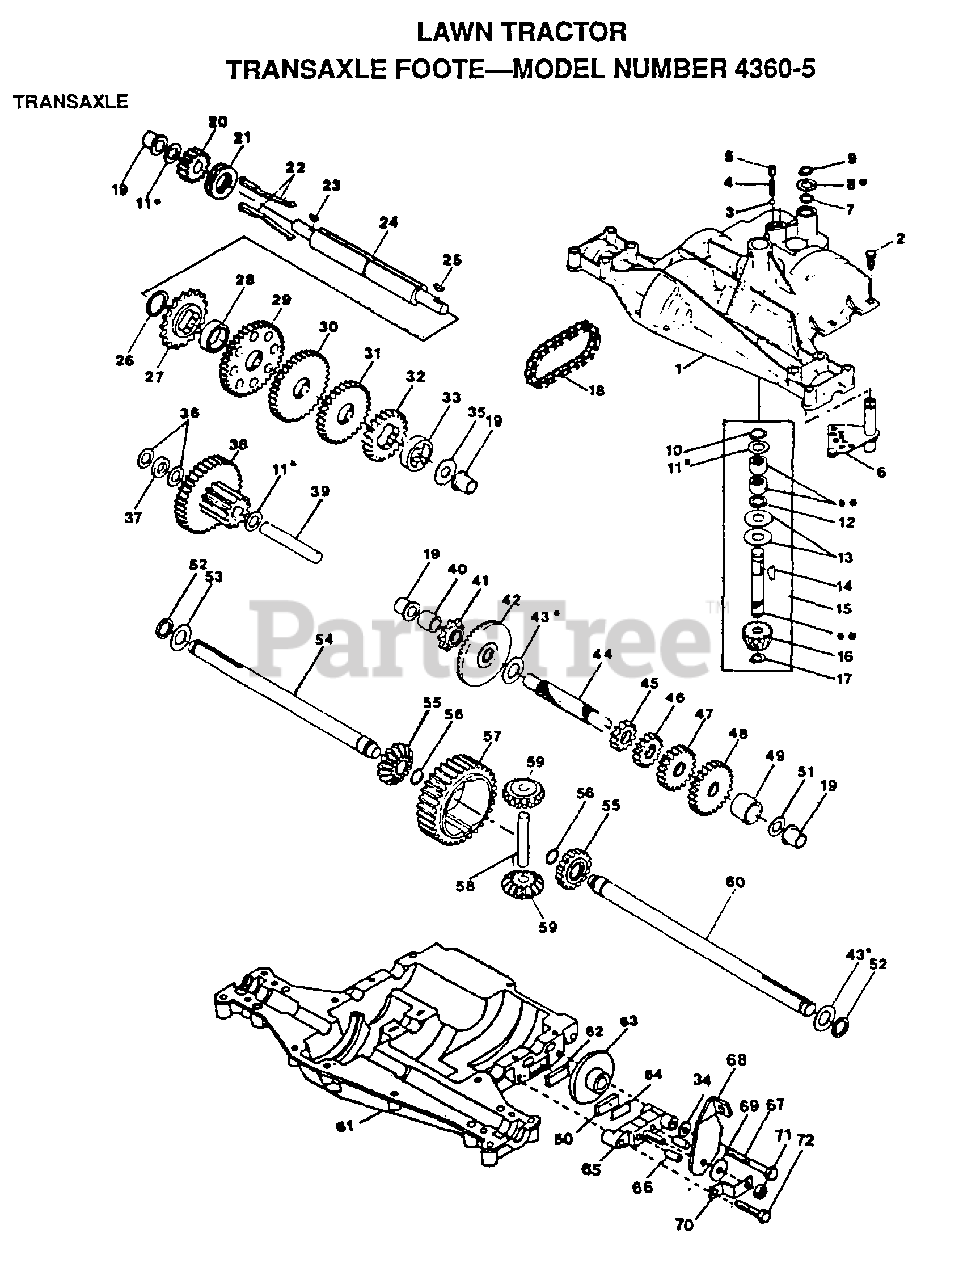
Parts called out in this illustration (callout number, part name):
1	HOUSING UPPER
3	BALL DETENT
4	SPRING, DETENT
5	SCREW, SET
6	ASSY SHIFTER
8	WASHER PLAIN
8A	WASHER PLAIN
8B	WASHER PLAIN
8C	WASHER PLAIN
8D	WASHER PLAIN
8E	WASHER PLAIN
8F	WASHER PLAIN
9	RING RETAINING
10	RING RETAINING
11	WASHER PLAIN
11A	WASHER PLAIN
11B	WASHER, PLAIN .632 X 1.00 X .026
11C	WASHER PLAIN
11D	WASHER PLAIN
11E	WASHER PLAIN
11F	WASHER PLAIN
11G	WASHER PLAIN
11H	WASHER, PLAIN .632 X 1.00 X .060
11I	WASHER PLAIN
13	WASHER, PLAIN .632 X 1.38 X .046
14	KEY WOODRUFF #9
15	ASSY KIT INPUT SHAFT
16	PINION, BEVEL, 14 TEETH
17	RING, RETAINING
18	CHAIN, 24 PITCHES
19	BEARING, FLANGE
20	GEAR SPUR, 14 TEETH
21	COLLAR CLUTCH
22	KEY CLUTCH
23	KEY WOODRUFF #3
24	SHAFT INTERMEDIATE
25	KEY, WOODRUFF, #61
26	RING, RETAINING
27	SPROCKET, 18 TEETH
29	GEAR, SPUR, 37 TEETH
30	GEAR, SPUR, 30 TEETH
31	GEAR, SPUR, 25 TEETH
34	WASHER PLAIN
35	WASHER, PLAIN .640 X 1.37 X .061
36	WASHER, PLAIN .632 X 1.00 X .026
37	SPACER .630 X 1.00 X .169
38	ASSY GEAR COMB 12&35 TEETH
39	SHAFT IDLER
40	SPACER .635 X .875 X .755
41	SPROCKET, 9 TEETH
42	GEAR, BEVEL, 42 TEETH
43	WASHER PLAIN
43A	WASHER PLAIN
43B	WASHER PLAIN
43C	WASHER PLAIN
43D	WASHER PLAIN
43E	WASHER PLAIN
43F	WASHER, PLAIN .758 X 1.25 X .031
43G	WASHER PLAIN
43H	WASHER PLAIN
43I	WASHER PLAIN
43J	WASHER PLAIN
43K	WASHER PLAIN
43L	WASHER PLAIN
44	SHAFT, DRIVE
45	GEAR, SPUR, 12 TEETH
46	GEAR, SPUR, 20 TEETH
47	GEAR, SPUR, 25 TEETH
48	GEAR, SPUR, 31 TEETH
49	SPACER .781 X 1.00 X .750
50	PUCK, FRICTION
51	WASHER, PLAIN .632 X 1.00 X .060
53	WASHER PLAIN
54	AXLE LEFT HAND
55	GEAR, MITER, 15 TEETH
56	RING, RETAINING
57	GEAR, SPUR, 32 TEETH
58	SHAFT, CROSS
59	GEAR, MITER, 15 TEETH
60	AXLE, R.H.
61	HOUSING LOWER
62	PUCK, FRICTION
63	DISC, BRAKE
65	JAW, BRAKE
66	PIN, DOWEL
67	SCREW TAPPING
68	LEVER, ACTUATING
69	WASHER, PLAIN .321 X 1.00 X .055
70	BRACKET, ANTI-ROTATION
71	LOCKNUT 5/16-24
72	SCREW TAPPING
